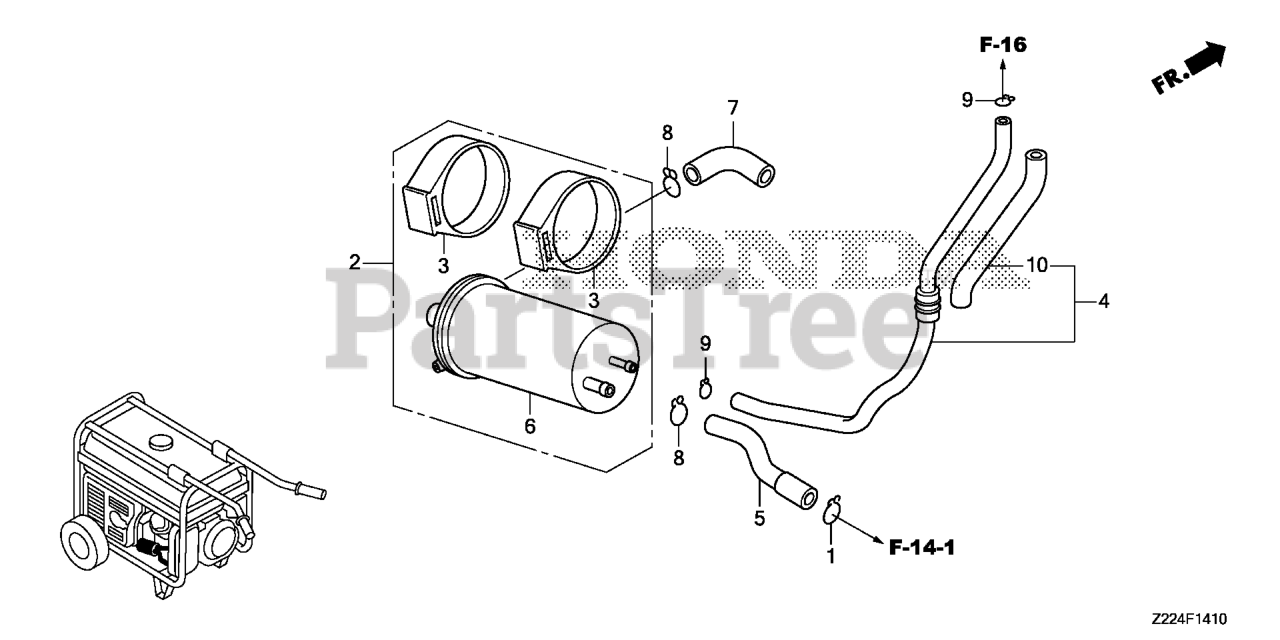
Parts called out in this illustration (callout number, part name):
1	CLIP, BREATHER TUBE
2	CANISTER ASSY.
3	RUBBER, CANISTER MOUNTING
4	TUBE CANISTER CHARGE
5	TUBE, CANISTER PURGE
6	CANISTER ASSY.
7	TUBE, CANISTER DRAIN
8	CLIP, TUBE
9	CLIP, TUBE (B8)
10	BULK HOSE, VINYL (9X11X3000) (9X11X150)
